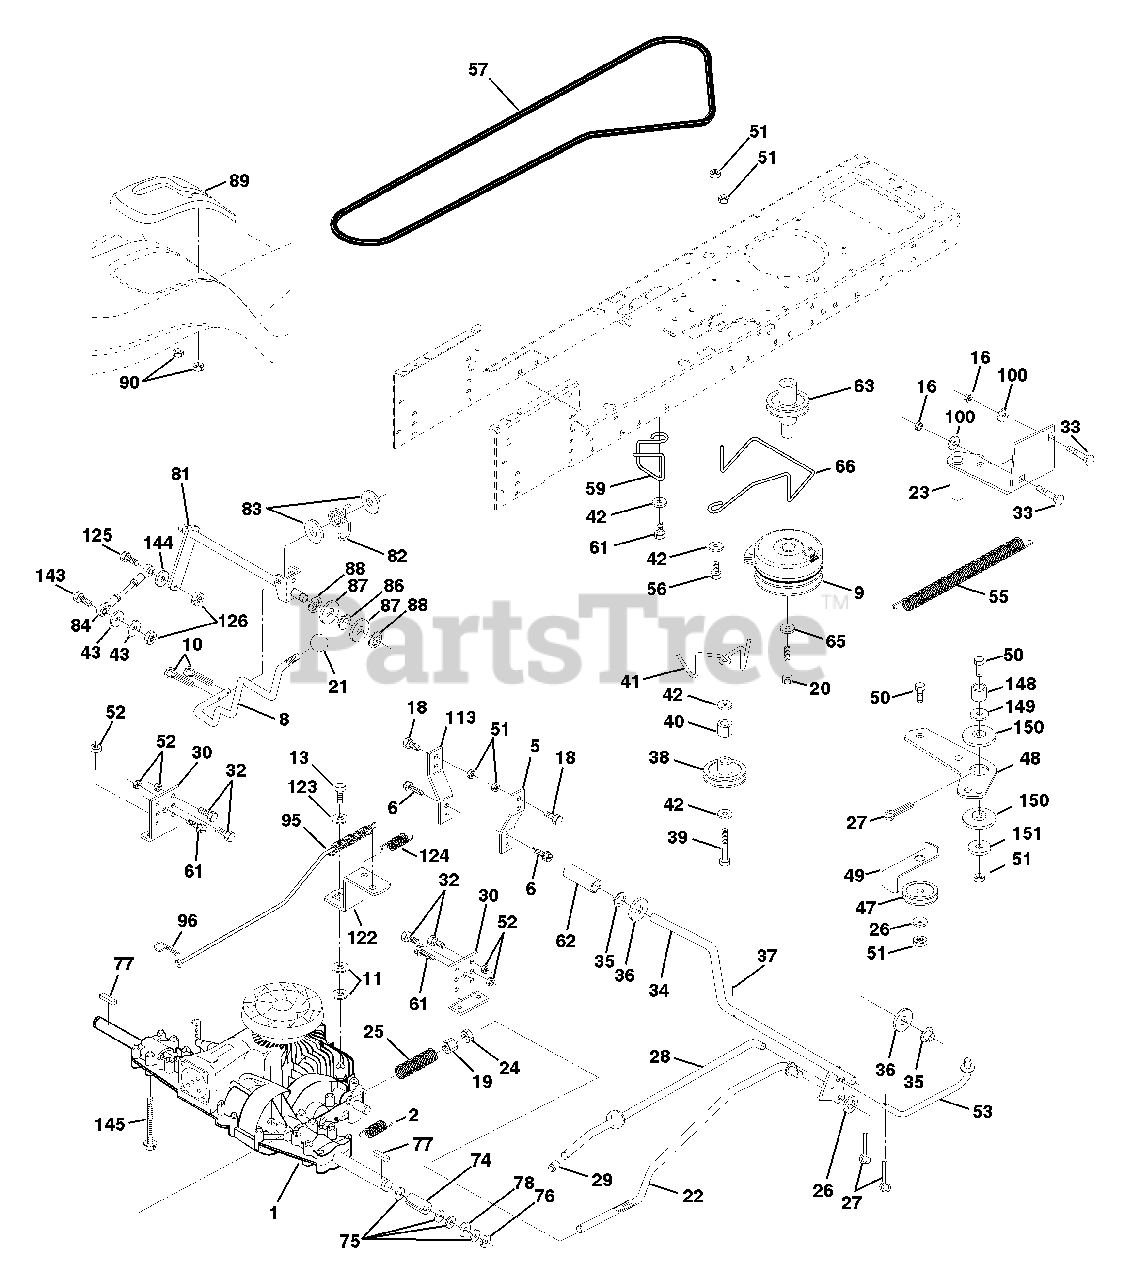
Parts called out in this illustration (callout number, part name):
1	Transaxle Peerless
2	Spring, Return, Brake
5	Strap Torque
6	Screw Thdrol 5/16-18 x 3/4
8	Rod Shift Hydro LT
9	Clutch Electric
10	Pin Cotter 1/8 x 1 CAD
11	Washer Plate Shf 388 Sq Hole
13	Bolt 1/4-28 Unf Gr. 8 W/Patch
15	Bolt Hex 5/16-18 Unc Flghd
16	Nut Lock Hex W/Ins. 5/16-18 Unc P
18	Bolt Fin Hex 3/8-16 Unc x 1 Gr.5
19	Nut Lock Hex W/Ins 3/8-16 Unc
20	Bolt, Hex 7/16-20 x 4-1/4 Ga. 5
21	Knob Deluxe 1/2-13 UNC BLK/BLK
22	Rod, Brake Hydro
23	Bracket Asm Mtg CL
24	Nut Hex Jam 3/8-16 UNC
25	Spring, Brake Rod
26	Washer
27	Pin Cotter 1/8 x 3/4 CAD.
28	Rod, Parking Brake
29	Cap, Parking Brake
30	Bracket, Transaxle
32	Bolt Hex Hd 5/16-18 Unc x 3/4
33	Bolt Carriage 5/16-18 UNC x 3/4
34	Shaft, Foot Pedal
35	Bearing, Nylon
37	Pin, Roll
38	Pulley, Idler, Flat
40	Spacer Split
41	Keeper, Belt Idler
42	Washer 13/32 x 13/16 x 12 Ga
43	Washer 11/32 x 5/8 x 12 Ga.
47	Pulley, Idler, V-Groove Plastic
48	Bellcrank Assembly
49	Retainer, Belt Style Spring
50	Bolt
52	Nut Crown Lock 5/16-18
53	Link, Clutch
55	Spring, Return, Clutch
56	Bolt, Fin Hex 3/8-16 UNC x 1 1/4
57	V-Belt, Ground Drive
59	Keeper, Center Span
61	Screw Thdrol. 3/8-16 x 3/4 Ty. TT
62	Cover, Pedal Premium
63	Pulley, Clutch
65	Washer Lock Hvy HLCL Spr 7/16
66	Keeper Belt Engine
74	Spacer, Split
75	Washer 25/32 x 1-1/4 x 16 Ga.
77	Key, Square
78	Washer 25/32 x 1-5/8 x 16 Ga
81	Shaft Asm. Cross Hydro 20" Tires
82	Spring Torsion T/A
83	Washer 17/32 x 3/4 x 16 Ga.
84	Rod, Tie Hydro 20" Tires SPH Ball 4.75
86	Bushing Rod Strig. 629/632 ID
87	Washer 21/32 x 1-1/4 x 16 Ga.
88	Ring Klip #5304-62
89	Console, Hydro STLT
90	Nut Self-Thd Wsh-Hd 1/4 Zinc
95	Control Asm. Bypass Hydro
96	Retainer Spring 1" Zinc/Cad
100	Washer 11/32 x 3/4 x 16 Ga.
113	Strap Torque LH LT
118	Spacer Bellcrank
121	Nyliner Clutching STL
122	Plate Bypass PVST
123	Washer 9/32 x 5/8 x 16 Ga.
124	Spring Return PVST
125	Bolt Fin Hex 5/16-18 UNC x 1
126	Nut Lock 5/16-18 UNC
143	Bolt Fin Hex 5/16-18 unc x 1-1/4
